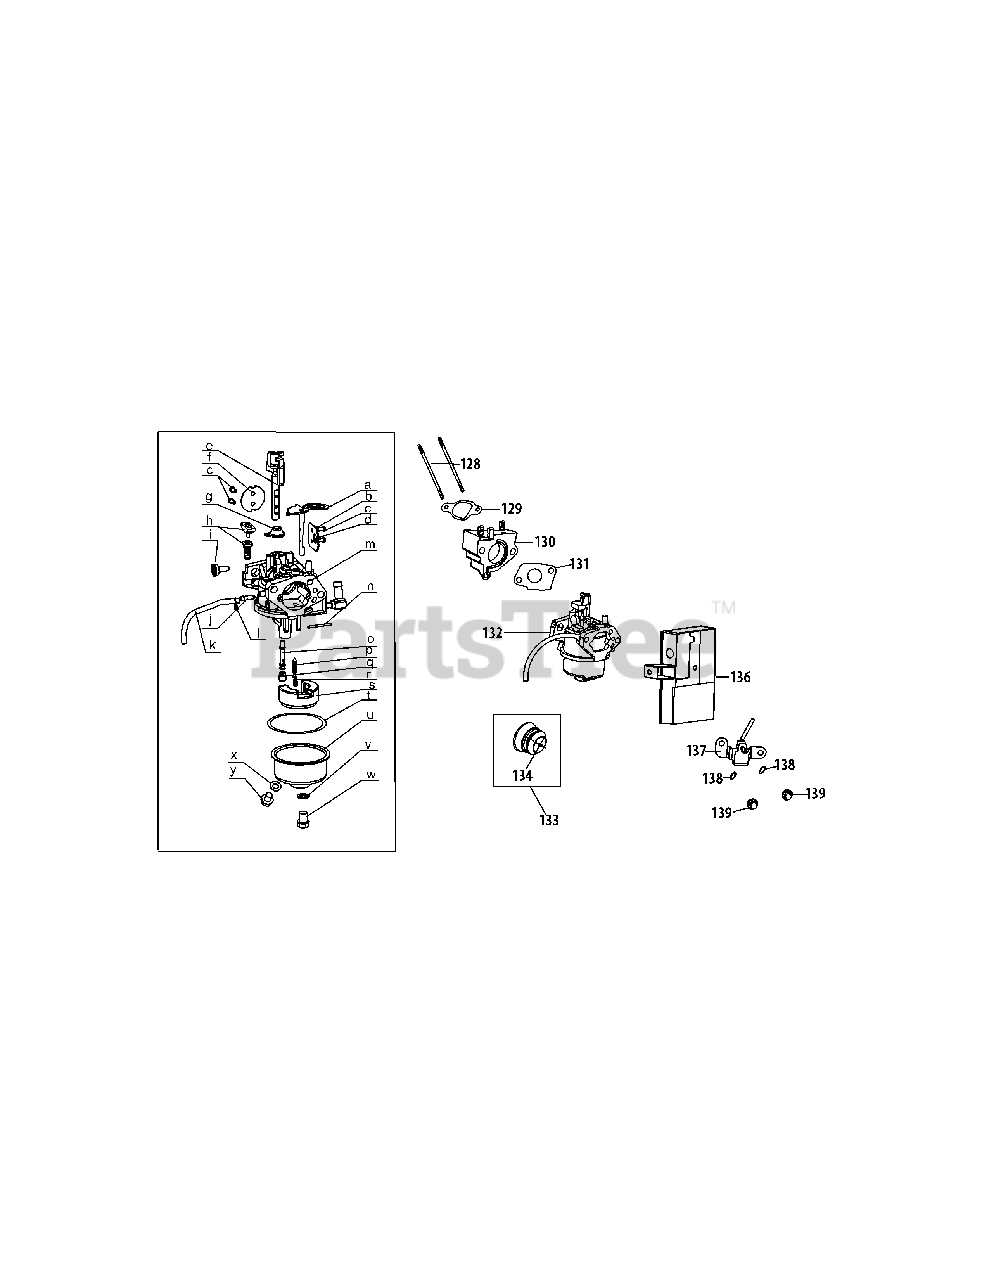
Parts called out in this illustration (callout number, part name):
128	Stud M6-8×106
129	Carburetor Insulator Gasket
130	Carburetor Insulator
131	Carburetor Gasket
132	Carburetor Assembly
133	Primer Assembly
134	Primer Bulb
136	Heater Box
137	Choke Control
138	Lock Washer
139	Nut M6
